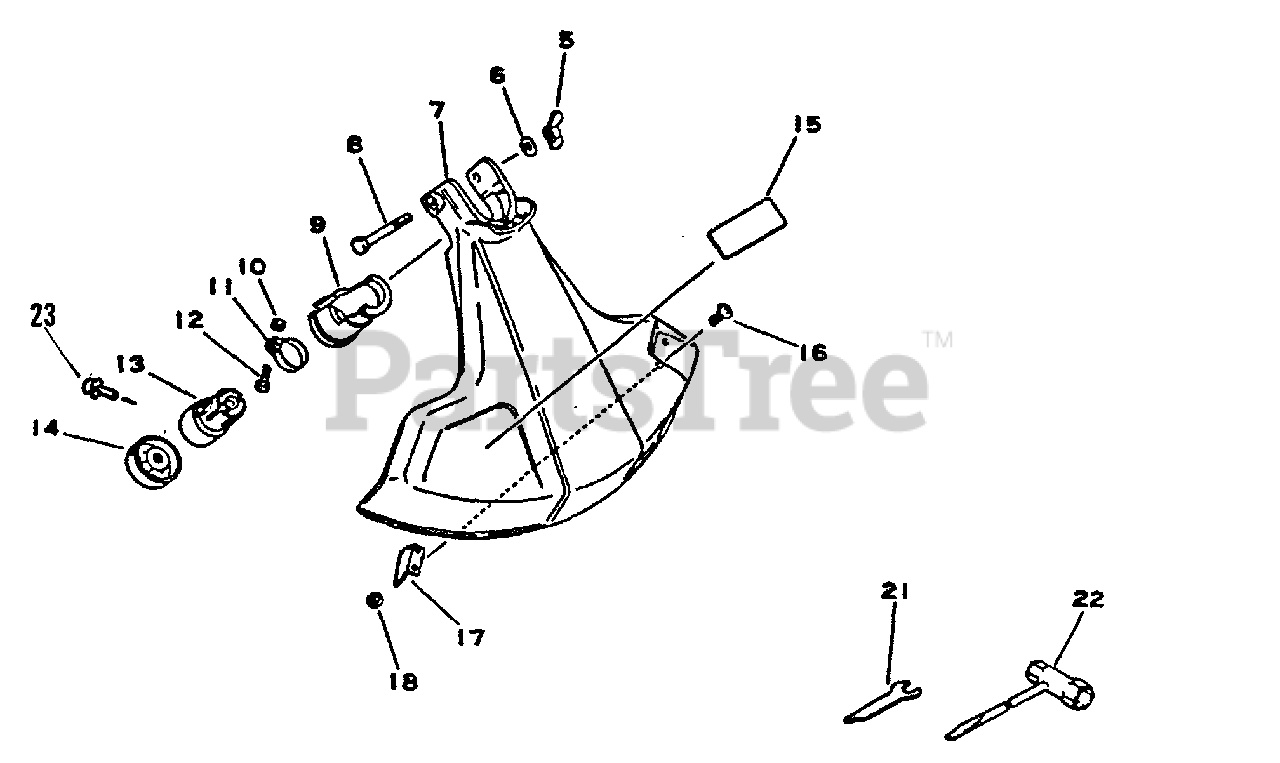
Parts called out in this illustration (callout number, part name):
5	WINGNUT - 6
6	WASHER - 6
7	SHIELD, DEBRIS - PLASTIC
8	BOLT - 6X50
9	BRACKET, BEARING CASE
13	GEAR CASE ASSY
14	ADAPTOR, BLADE - UPPER
15	LABEL - ECHO
16	SCREW - 5X16
17	KNIFE, TRIMMER LINE
18	NUT - 5
21	SPANNER - 10mm
22	T-WRENCH - 8X19mm
23	SCREW - 4X10
